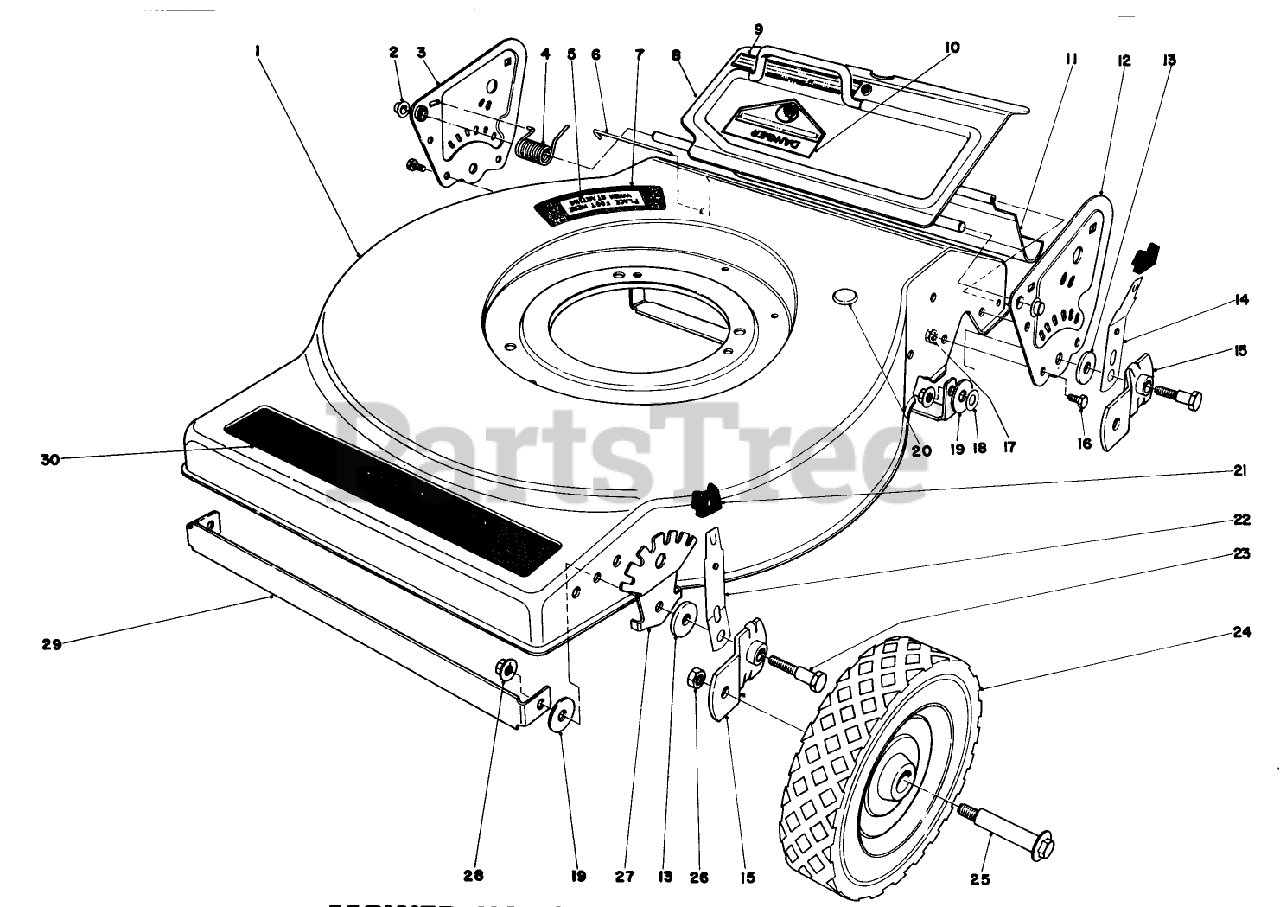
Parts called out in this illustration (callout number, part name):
2	NUT-PUSH
3	Side Plate R.H
10	DECAL-DANGER
11	Rear Shield
13	PIVOT WASHER
14	Spring Arm
15	PIVOT ARM ASM A
16	SCREW-HH
17	NUT-LOCK, CONE
18	WASHER-PLAIN
21	KNOB-ARM
22	SPRING ARM ASM
23	PIVOT SCREW
